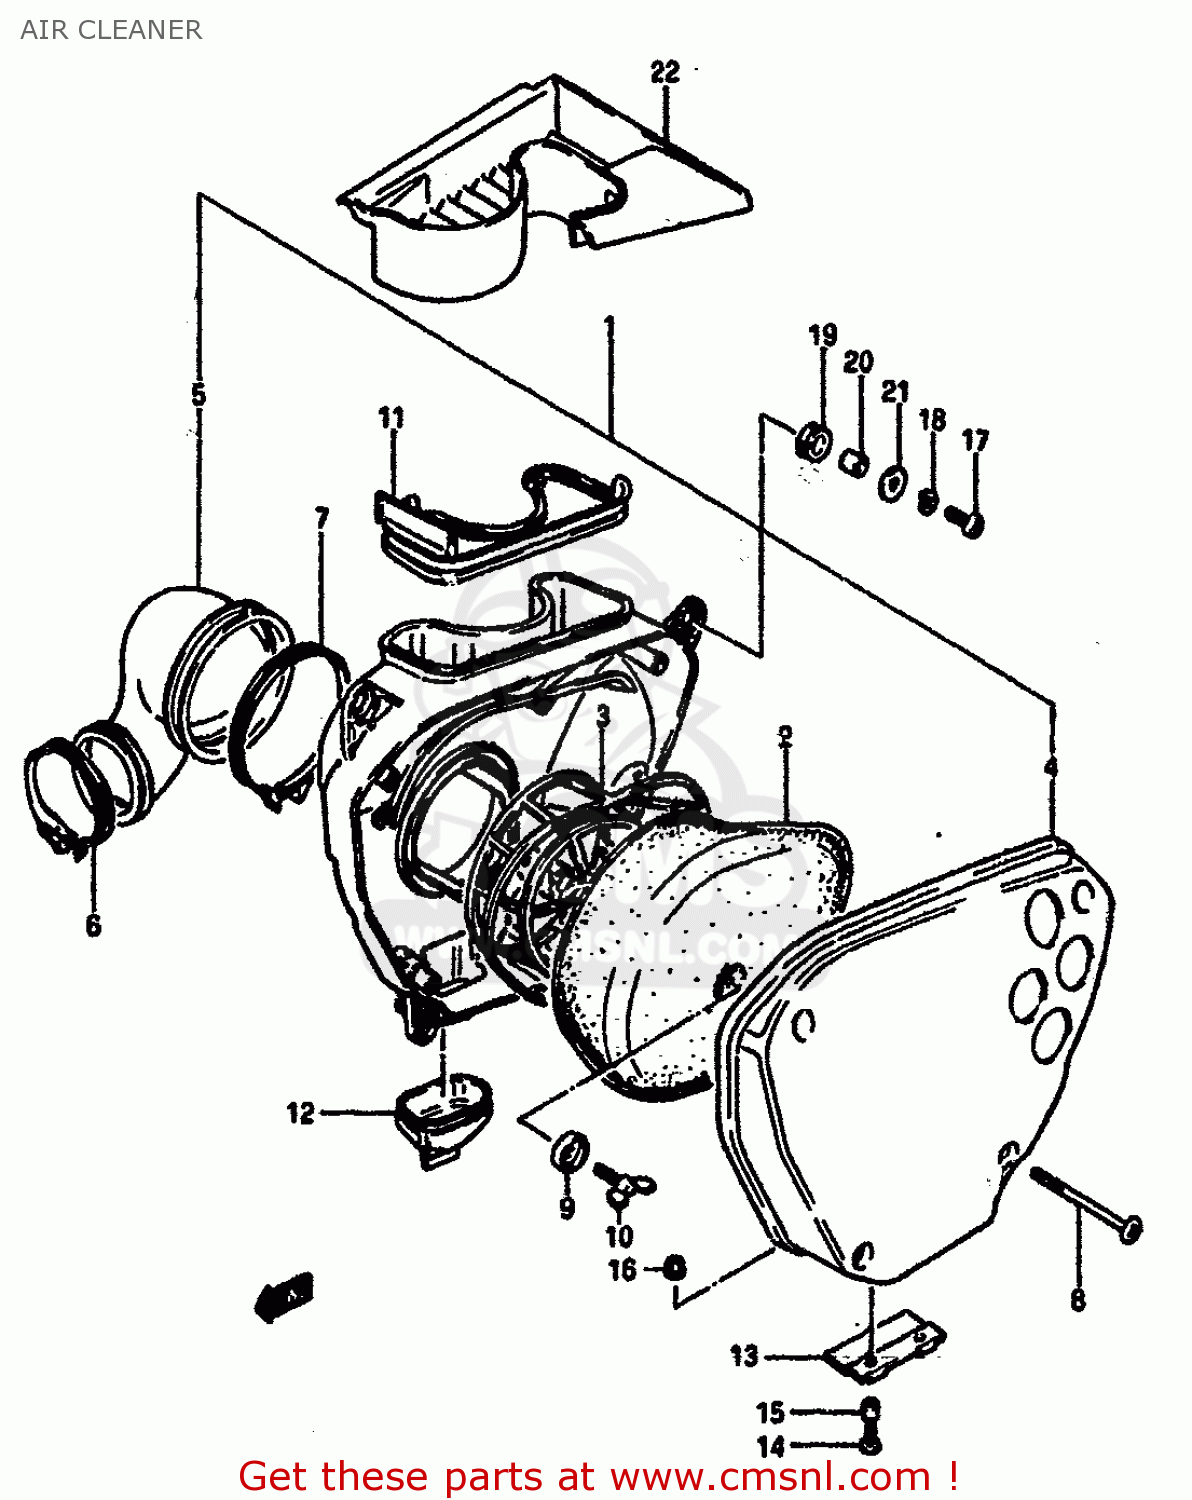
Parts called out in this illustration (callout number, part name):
1	CLEANER ASSEMBLY,AIR
2	FILTER,AIR CLEANER
3	HOLDER,AIR CLEANER
4	CAP,AIR CLEANER
5	TUBE,AIR CLEANER OUTLET
6	CLAMP
7	CLAMP
8	SCREW
9	WASHER,FILTER HOLDER
10	BOLT,AIR CLEANER
11	GUARD,MUD
12	TUBE,DRAIN
13	SHEET,AIR CLEANER
14	SCREW
15	COLLAR
16	NUT
17	SCREW
18	LOCK WASHER
19	CUSHION
20	SPACER (7X9X7)
21	WASHER
22	GUIDE,AIR CLEANER NO.2 MU
